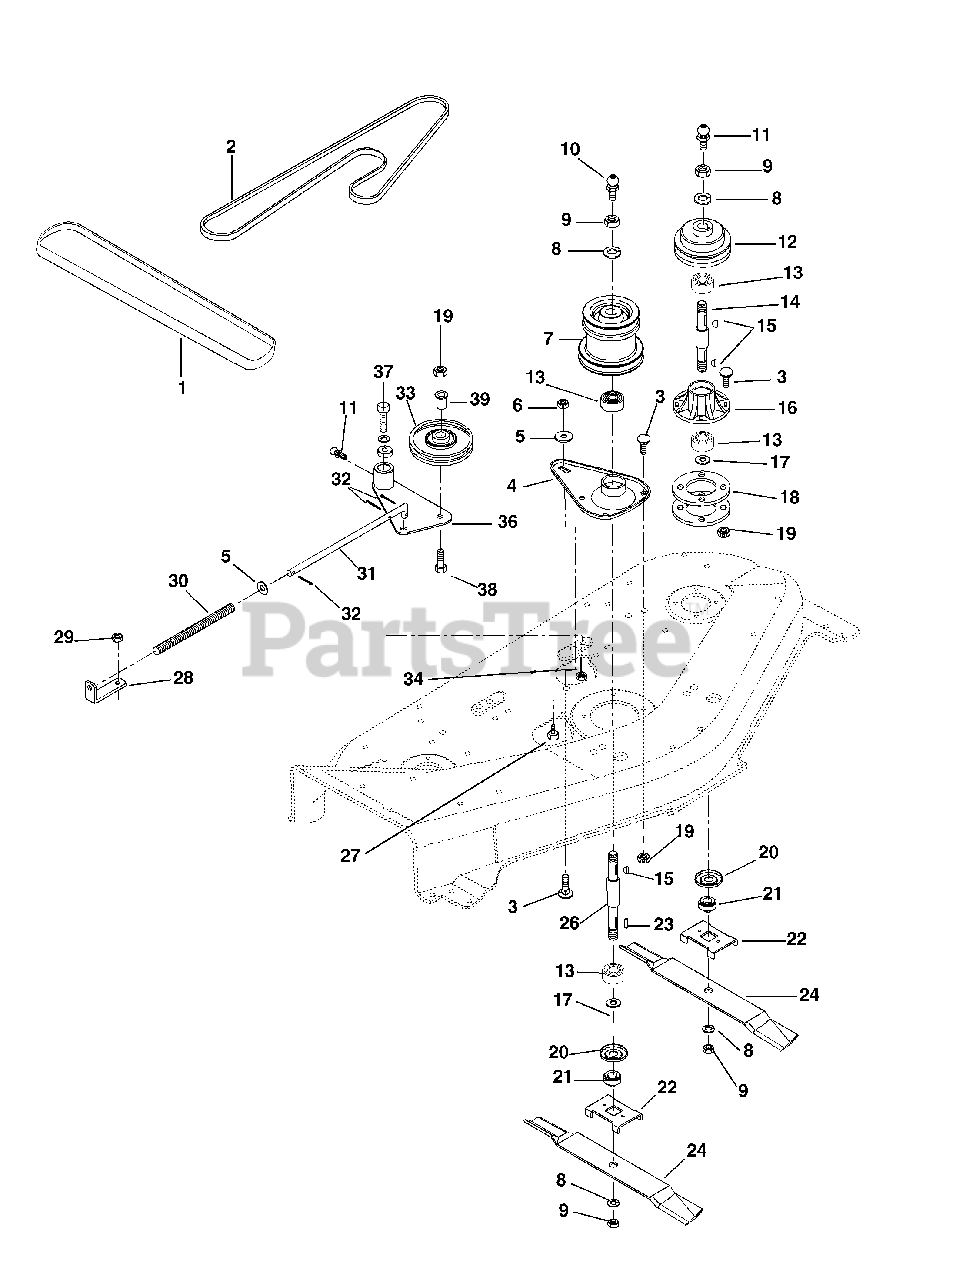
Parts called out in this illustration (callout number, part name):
1	V-BELT, HA-WRAPPED
2	V-BELT, HA-RAW EDGE
3	@BLT-RDHDSQNK .38-16X.75 G5YZ
4	HOUSING, SPINDLE
5	@WSHR-FL-STL.406X.812X.065 YWZ
6	@NUT-LK-CTR .38-16 YWZC
7	SHEAVE, 48" DECK
8	@WSHR-LK .75X.188 REG YWZC
9	NUT-JAM .75-10 YWZC
10	FTG,LUBE 1/8
11	FTG-LUBE .25-28X.256 YWZC
13	BRG-BALL .750X1.781X.61
14	SPINDLE SHAFT W/ZERK
15	KEY-WDRF .188X.625X.25 SAE 61
16	SPINDLE HOUSING
17	WSHR-FL-STL .754X1.000X.032 YZ
18	SPACER, SPINDLE
19	@NUT-LK-TOP-FLG .38-16 YWZC
20	BEARING SLINGER
21	RETAINER HUB
22	BLADE TRAY 48
23	KEY-SQ .188X.625X.188 SAE 61
25	WSHR-FL-STL .755X1.25X.125 YZ
26	SPINDLE SHAFT W/ZERK & KEY
27	@BLT-HEX .31-18X.50 GR5 YWZC
28	BRACKET
29	@NUT-LK-CTR .31-18 YWZC
30	SG-COMP .106X.63X 12.0 WLD 62
31	ROD-IDLER SPRING
32	@PIN-CTR .09X.75 EXTPRSQCT YWZ
33	IDLER, PLASTIC, 4.00 X .50 ID
34	@NUT-LK-CTR .50-13 YWZC
35	WSHR-FL-STL .505X.880X.072 YWZ
36	IDLER ARM
37	@BLT-HEX .50-13X2.50 GR5 YWZC
38	BLT-BTHD .38-16X1.25 GR5
39	SPACER -FLANGED .390X.500X.781
40	SPACER, PIVOT .500X.750X1.805
